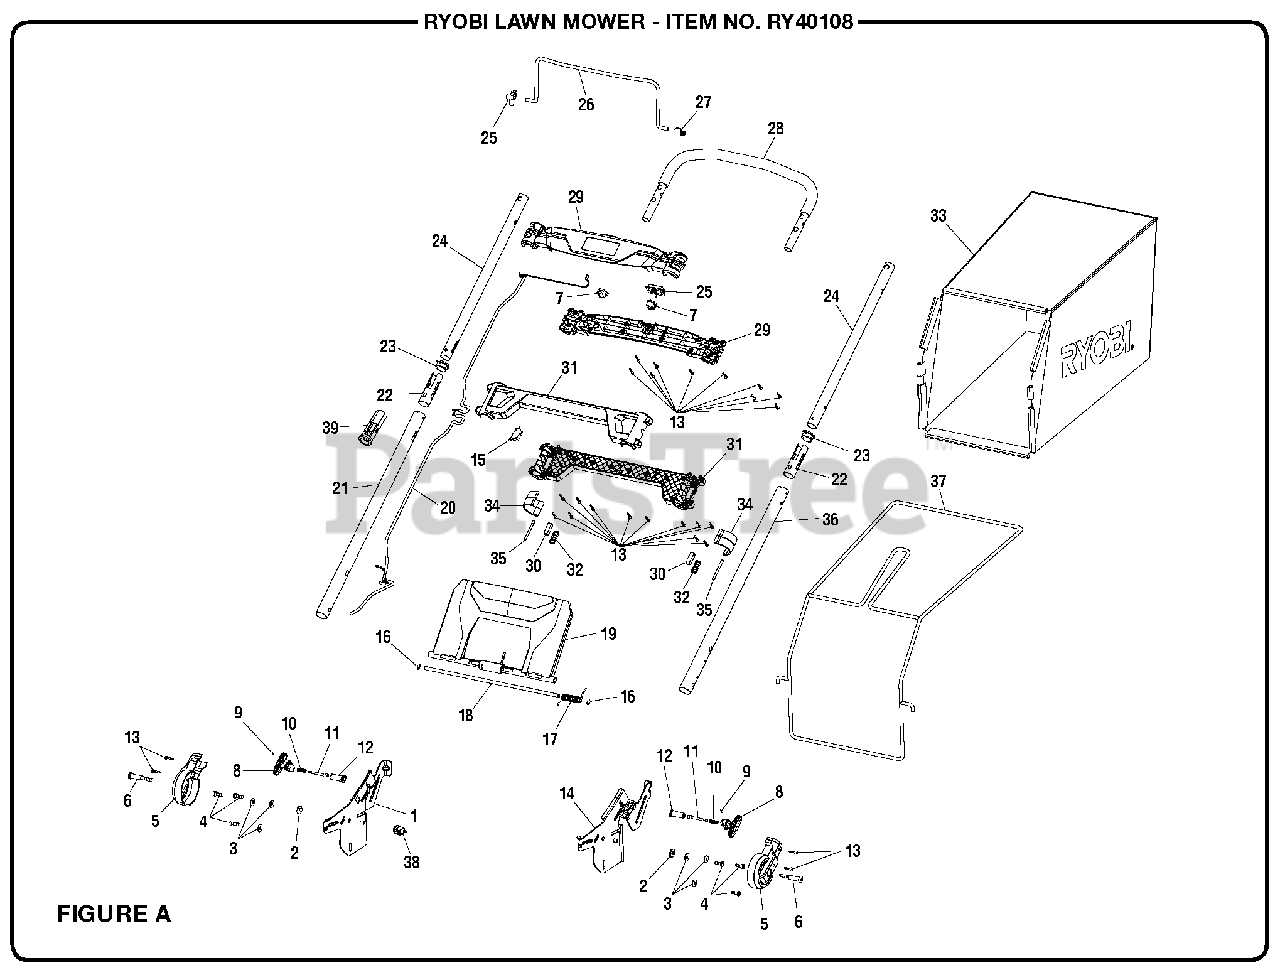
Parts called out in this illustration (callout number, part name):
1	Height Adjustment Bracket (Right)
2	Washer (ID8.5 x OD20.5 x 3t)
3	Washer (1/4 in.)
4	Screw (1/4-15 x 3/4 in., T30 Torx Pan Hd.)
5	Hinge Cover
6	Shoulder Screw (M8 x 60 mm, T40 Torx Hd.)
8	Adjustment Knob (Spring Pin)
9	Spring Pin
10	Compression Spring
11	Detent Pin
12	Spring Pin Housing
13	Screw (M4 x 18 mm, T20 Torx Pan Hd.)
14	Height Adjustment Bracket (Left)
17	Torsion Spring (Rear Door)
18	Rear Door Axle
19	Rear Discharge Door
20	Wiring Harness (B.D.C. EU17175D020013-EU17175D020018)
20	Wiring Harness (A.D.C. EU17175D020013-EU17175D020018)
21	Lower Handle Tube (Right)
22	Handle Tube Bushing (Large)
23	Handle Tube Bushing (Small)
24	Upper Handle Tube
25	Switch Acutator Assembly
26	Bail Handle (Power Lever)
27	Torsion Spring
28	Upper Handle Assembly
29	Upper Panel Assembly
30	Rubber Plate (Handle Lock Clip)
31	Lower Panel Assembly
32	Block (Handle Lock Clip)
34	Handle Lock Clip
35	Pin (Handle Lock Clip)
36	Lower Handle Tube (Left)
37	Bag Frame
38	Switch Kit
39	Switch Plug Housing
